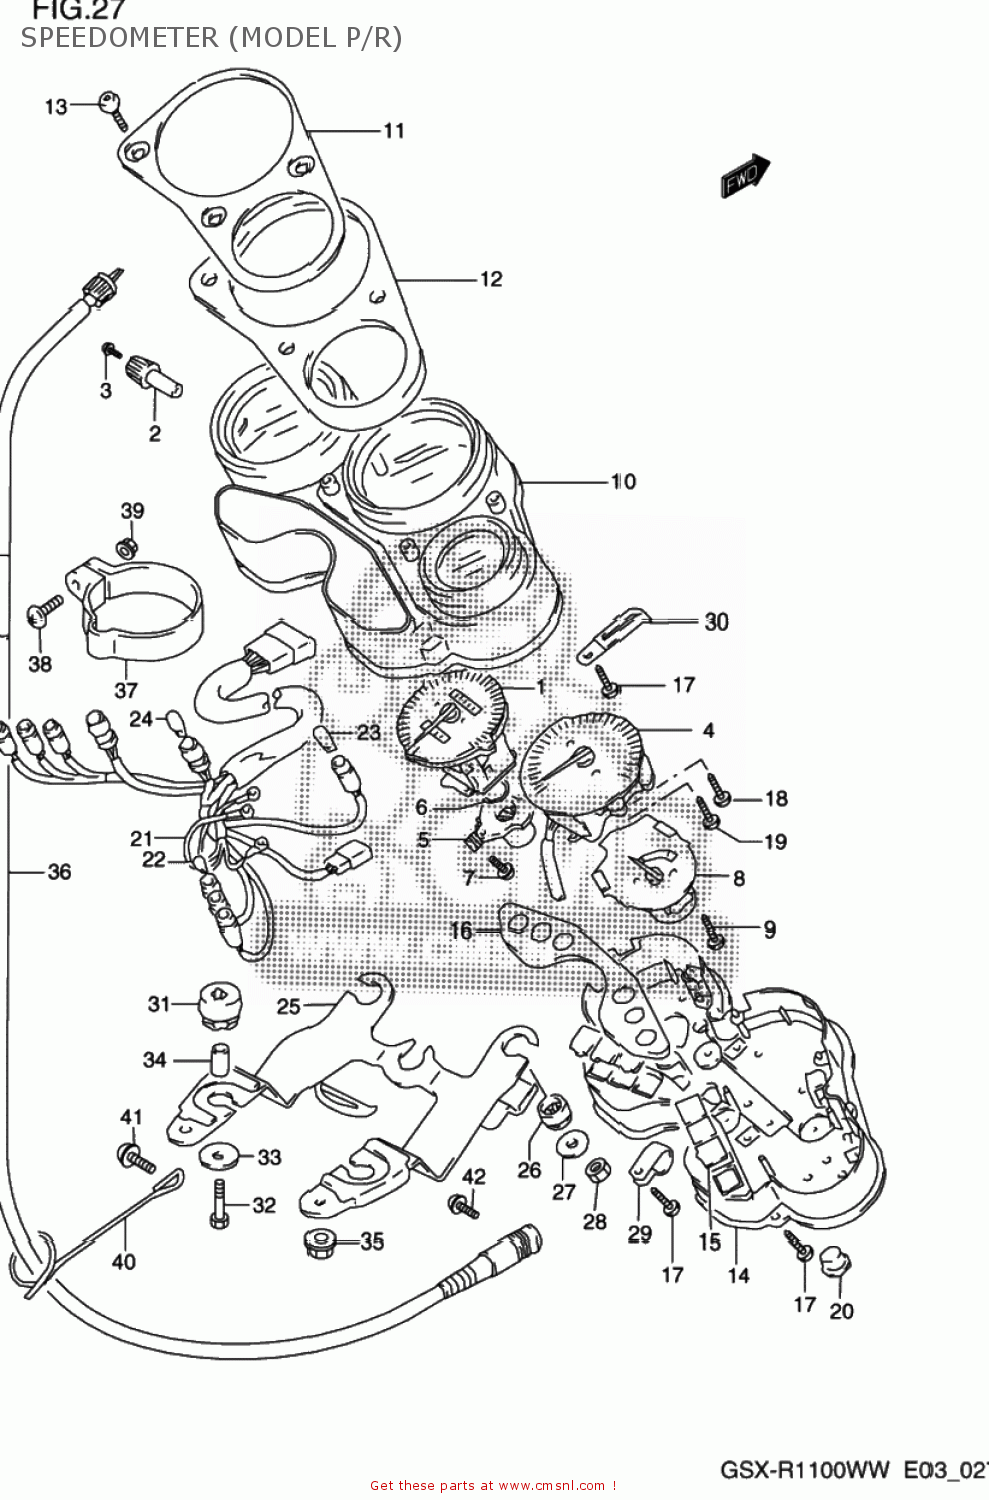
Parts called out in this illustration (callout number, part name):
1	SPEEDOMETER (KILO/MILE)
2	KNOB,TRIP
3	ROTOR,SPEED
4	TACHOMETER
5	GEAR BOX,SPEEDOMETER
6	O RING
7	SCREW
8	METER,TEMPERATURE
9	SCREW(3X22)
10	HOOD
11	PANEL,METER
12	CUSHION
13	SCREW
14	CASE,METER
15	LENS SET
16	PANEL
17	SCREW
18	SCREW(4X22)
19	SCREW (3X10)
20	CAP
21	SOCKET
22	BULB(12V3W,T6.5)
23	BULB(12V1.7W,T6.5)
24	BULB(12V1.7W,T10,WB121)
25	BRACKET,METER
26	CUSHION
27	WASHER,METER
28	NUT
29	CLAMP
30	CLAMP
31	GROMMET
32	BOLT
33	WASHER (6.5X20X1.6)
34	SPACER
35	NUT
36	CABLE ASSY,SPEEDOMETER
37	GUIDE,SPEEDOMETER CABLE
38	SCREW
39	NUT
40	GUIDE,SPEEDOMETER CABLE,R
41	SCREW
42	SCREW
